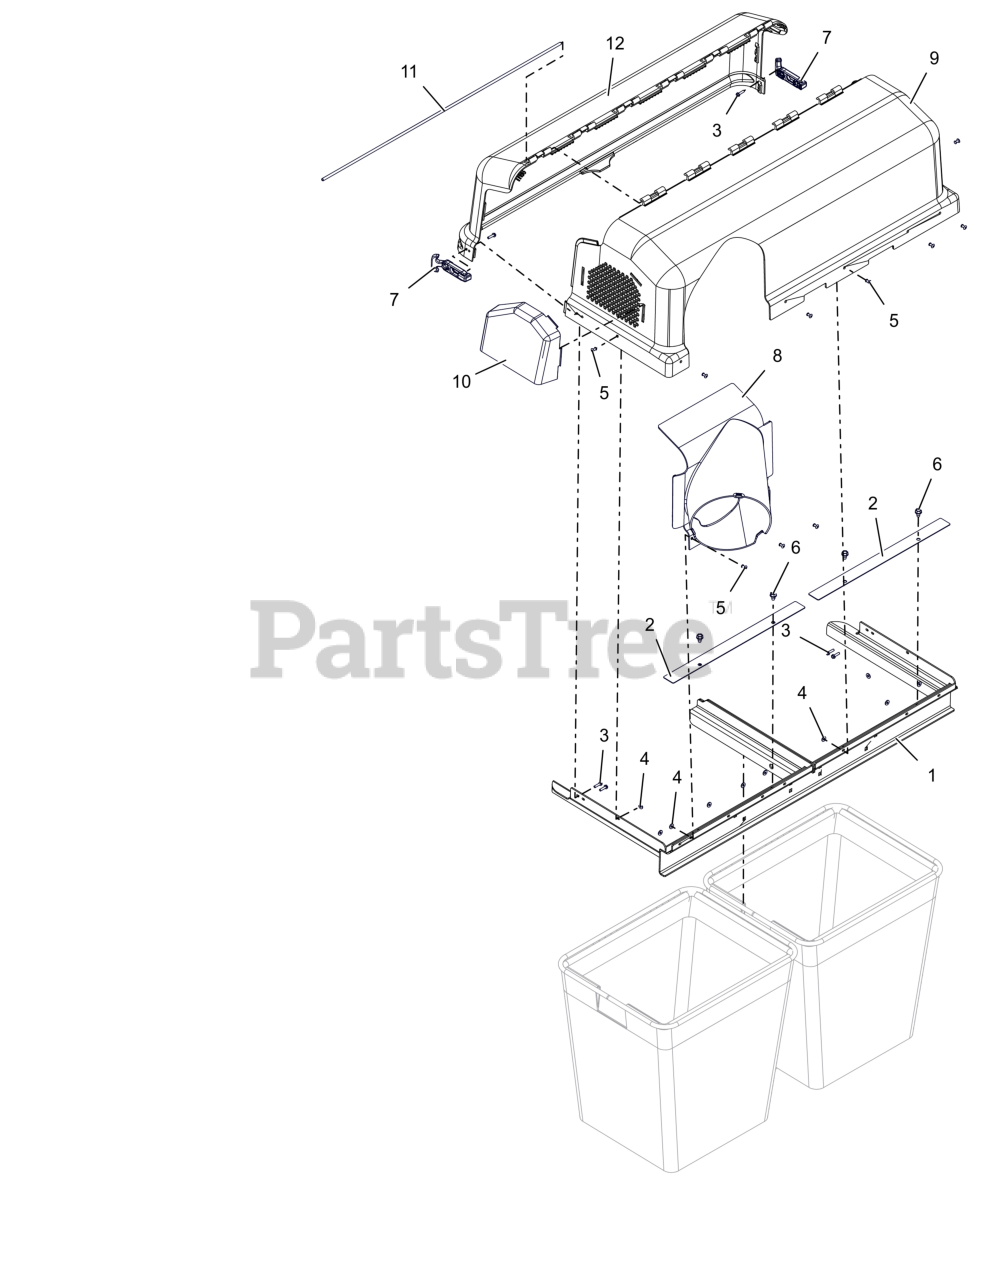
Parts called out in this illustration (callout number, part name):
1	WLDMT, BAGGER FRAME (BLACK)
2	BRKT-BAGGER OVERLAP
3	BLT, HWH #10-24X.75 ZCC
4	WSHR-FL-STL .196X.50X.06 ZC120
5	RIVET, #66 STEEL POP PD BLACK
6	SCR,TAP .312-18X.50 HWH TR ZCC
7	LATCH, RUBBER
8	INTAKE REAR, BAGGER
9	HOOD, REAR BAGGER
10	HOOD, VENT BAGGER
11	ROD, HINGE .25" X 32.5"
12	KIT- BAGGER DOOR W/DECAL
